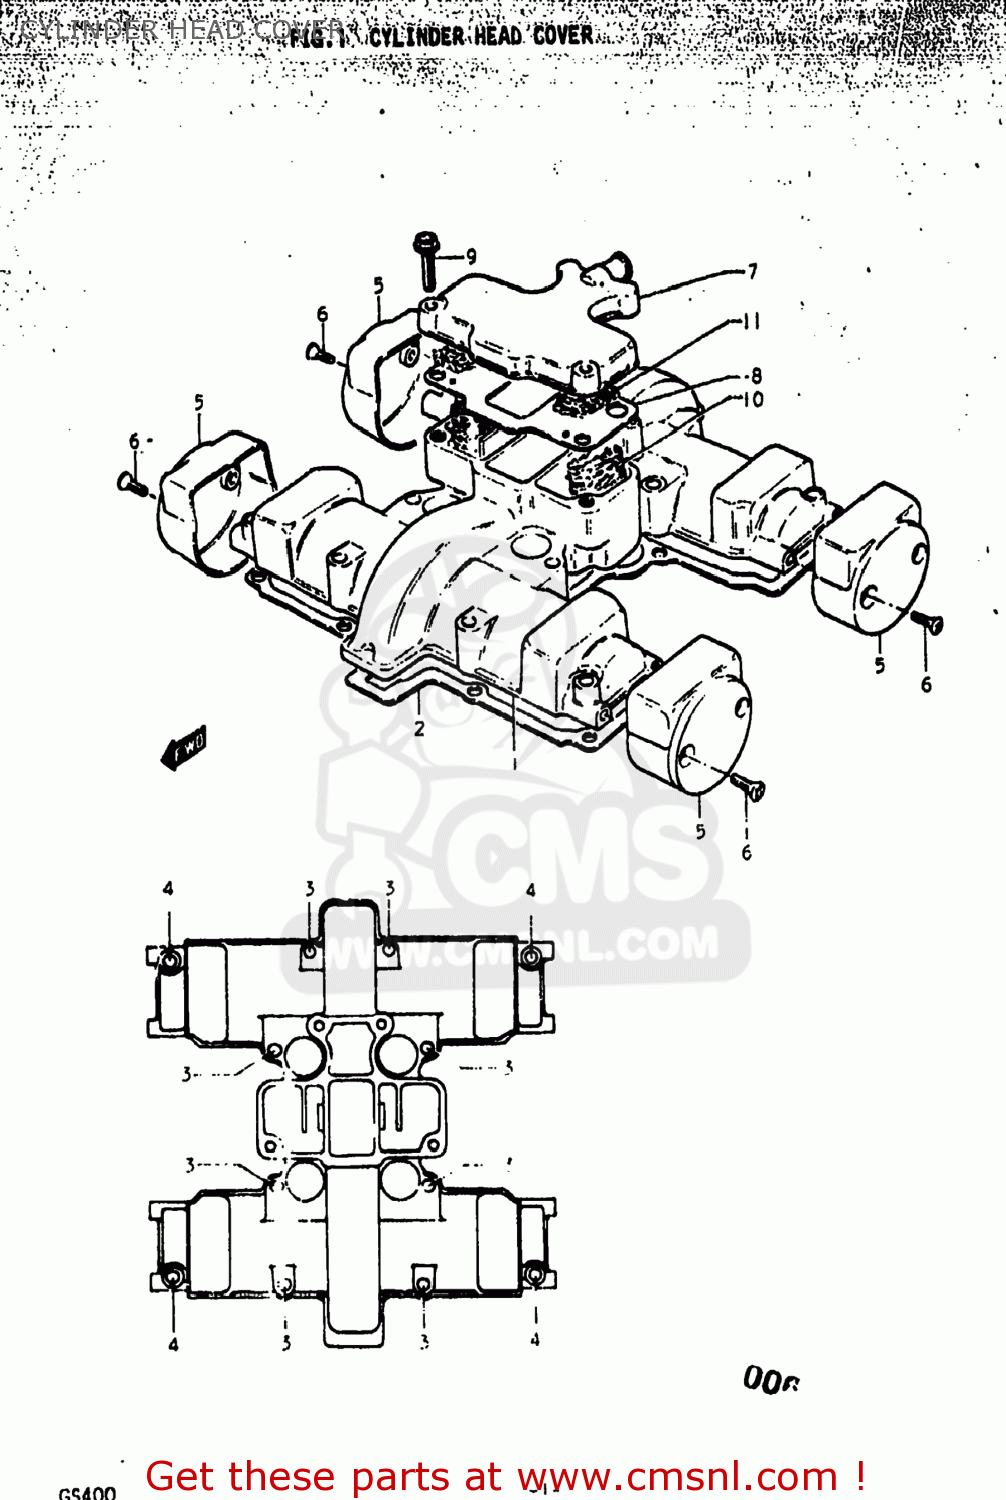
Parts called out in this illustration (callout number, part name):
1	COVER,CYLINDER HEAD
2	GASKET,CYLINDER HEAD COVER (MCA)
3	BOLT
4	BOLT
5	CAP,CYLINDER HEAD COVER
6	SCREW(5X12)
7	COVER,BREATHER
8	GASKET (MCA)
9	BOLT
10	COVER,BREATHER
11	SEPARATOR,OIL BREATHER
